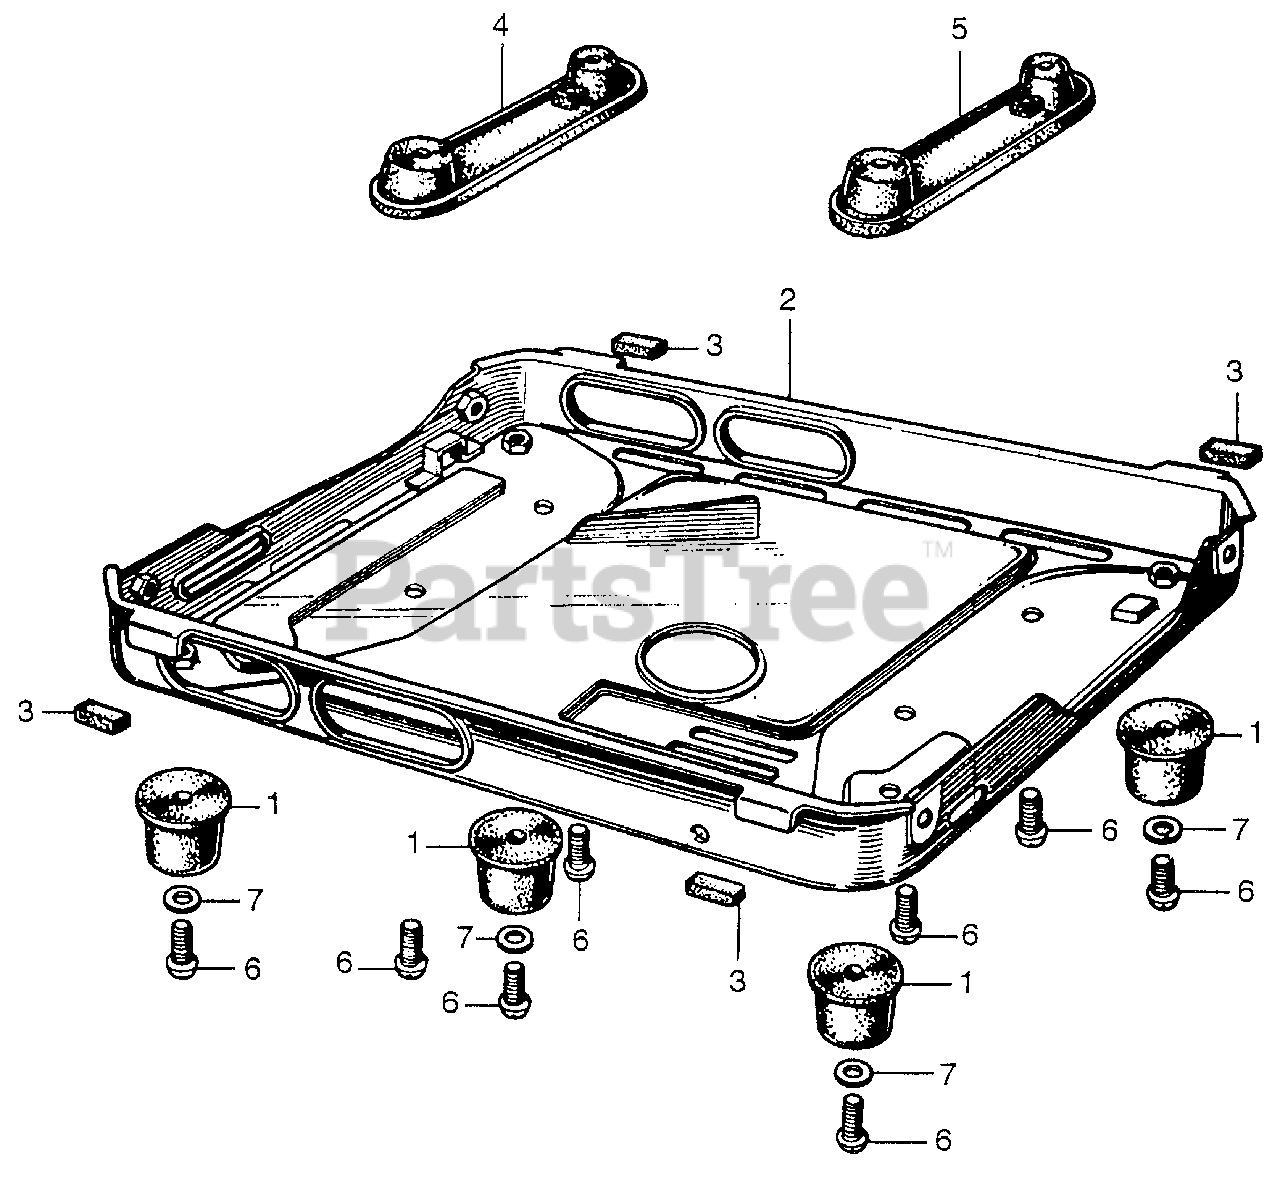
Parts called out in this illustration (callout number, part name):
1	RUBBER (LOWER)
2	COVER (LOWER) *NH1* (BLACK)
3	RUBBER, GUIDE
4	FRAME, ENGINE (NOT AVAILABLE)
5	FRAME, ALTERNATOR (NOT AVAILABLE)
6	SCREW, PAN (5X10)
7	WASHER, SPRING (5MM)
